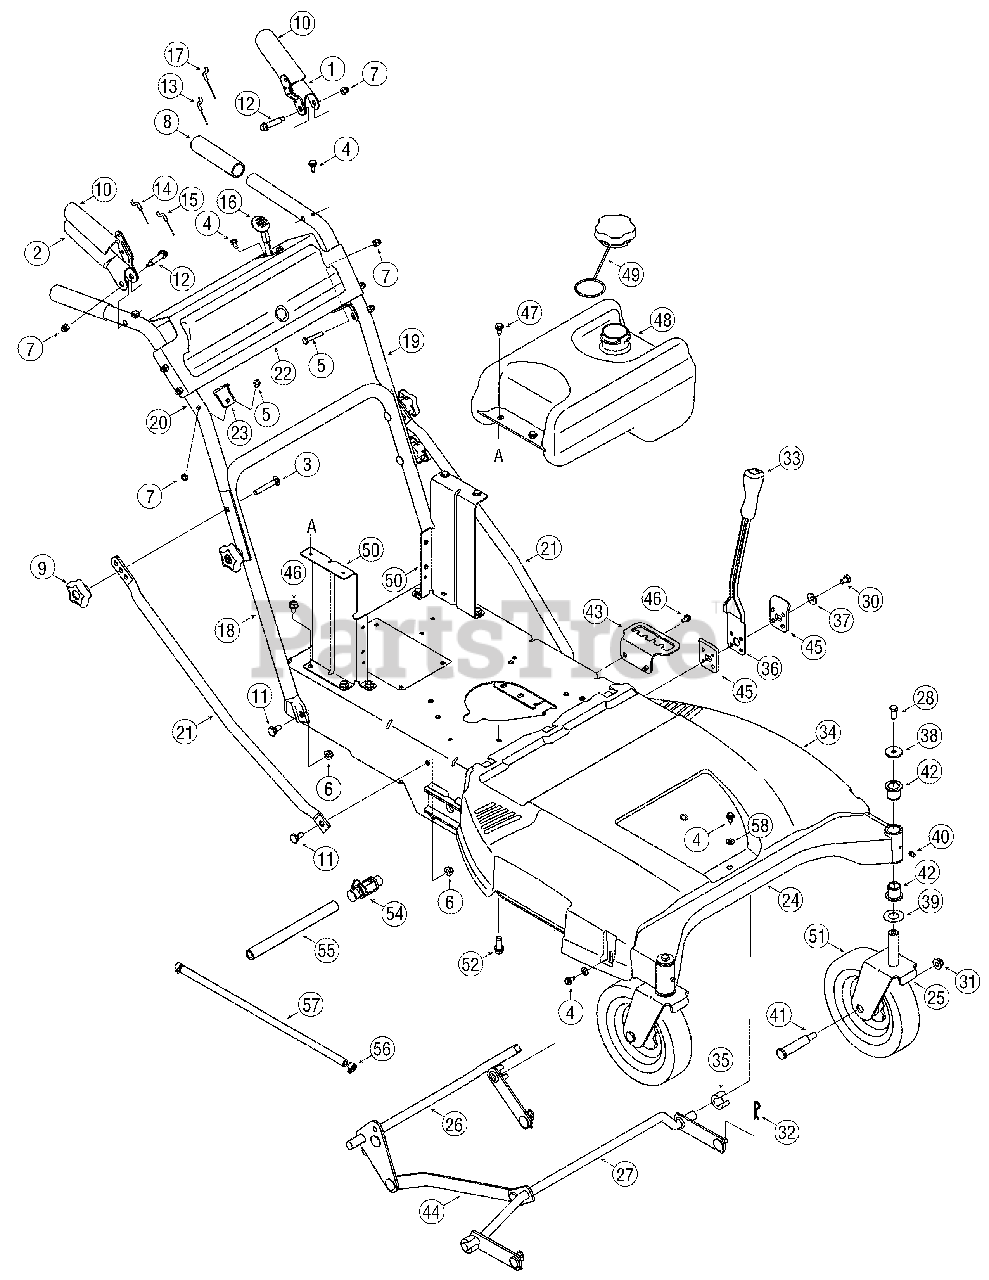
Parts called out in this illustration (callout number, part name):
4	Screw, TT: 1/4-20 x 0.500"
5	Screw, HH Cap: 1/4-20 x 1.50"
6	Nut, Flange Lock: 5/16-18
7	Nut, Lock Cap: 1/4-20
8	Grip: 1.0" ID x 5.0" Lg
9	Star Knob 5/16-18
10	Handle Grip
11	Screw, Shoulder: .435" x .178-5/16
12	Screw, Shoulder: .375" x 1.355" x 1/4-20
13	Cable, Clutch Wheel
14	Cable, Brake, Transmission: RH
15	Cable, Clutch Deck
16	Cable, Throttle/Choke: 38" x 1.1" Ext
17	Cable, Brake, Transmission: LH
28	Screw, HH Cap: 5/16-24 x .750"
29	Screw, HL: 1/4-15 x .50"
30	Screw, HH Cap: 5/16-18 x .50"
31	Nut, Flange Lock: 3/8-16
32	Click Pin: .092" x 1.64"
33	Handle Grip 1/2"
34	Belt Cover 33" Wide Cut Mower
35	Snap Spacer: .63" ID x .75" LG
36	Deck Height Lever
37	Washer, Bell: .340" x .872" x .060"
38	Washer, Flat: .330" x 1.25" x .120"
39	Washer, Flat: .760" ID x 1.50" OD
40	GREASE FITTING
41	Bolt, Shoulder: .625" x 2.515" x 3/8-16
42	Flange Bearing: .760" x .941" x 1.0"
46	Screw, TT: 5/16-18 x .625"
47	Screw, Shoulder: .3175" x .188" x 1/4-20
48	Fuel Tank, 2 Gal.
49	Fuel Cap
51	Wheel Caster 8" x 1.75" w/o bearings
52	Screw, TT: 3/8-16 x 1.25"
54	Oil Drain
55	Oil Drain Hose
56	Hose Clamp
57	Fuel Hose
58	Washer, Flat: .25 x .63 x .0515
